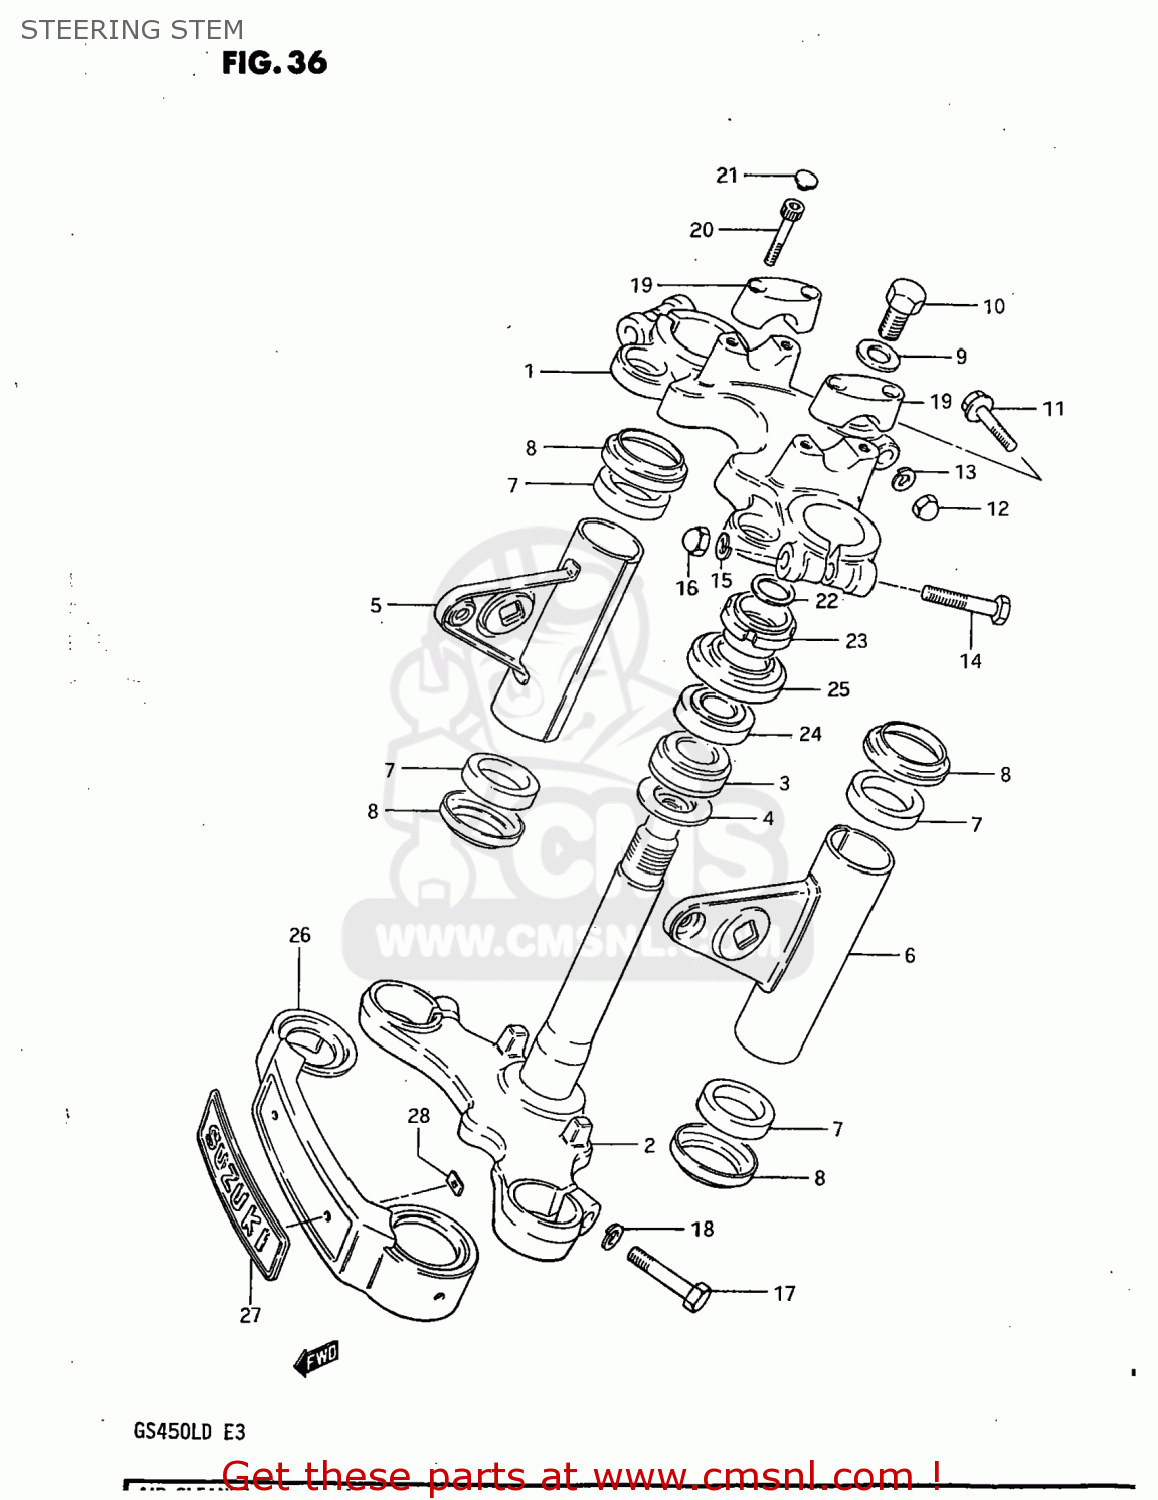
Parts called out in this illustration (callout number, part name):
1	HEAD,STEERING STEM
2	STEM,STEERING
3	BEARING
4	WASHER,THRUST
5	BRACKET,HEADLAMP,RIGHT
6	BRACKET,HEADLAMP,LEFT
7	CUSHION,HEADLAMP BRACKET
8	CAP,HEADLAMP BRACKET
9	WASHER (12.5X26X1.6)
10	BOLT 12X20
11	BOLT
12	NUT,M8X1.25X12
13	LOCK WASHER
14	BOLT 10X55
15	LOCK WASHER
16	NUT
17	BOLT 10X40
18	LOCK WASHER
19	HOLDER,HANDLEBAR(BLACK)
20	BOLT
21	CAP(OD:14.5)
22	WASHER(18.5X24X1)
23	NUT,STEERING STEM
24	TAPER,ROLLER BEARING
25	DUST SEAL,STEERING UPR
26	COVER,FRONT FORK
27	EMBLEM,FR FORK COVER
28	NUT
